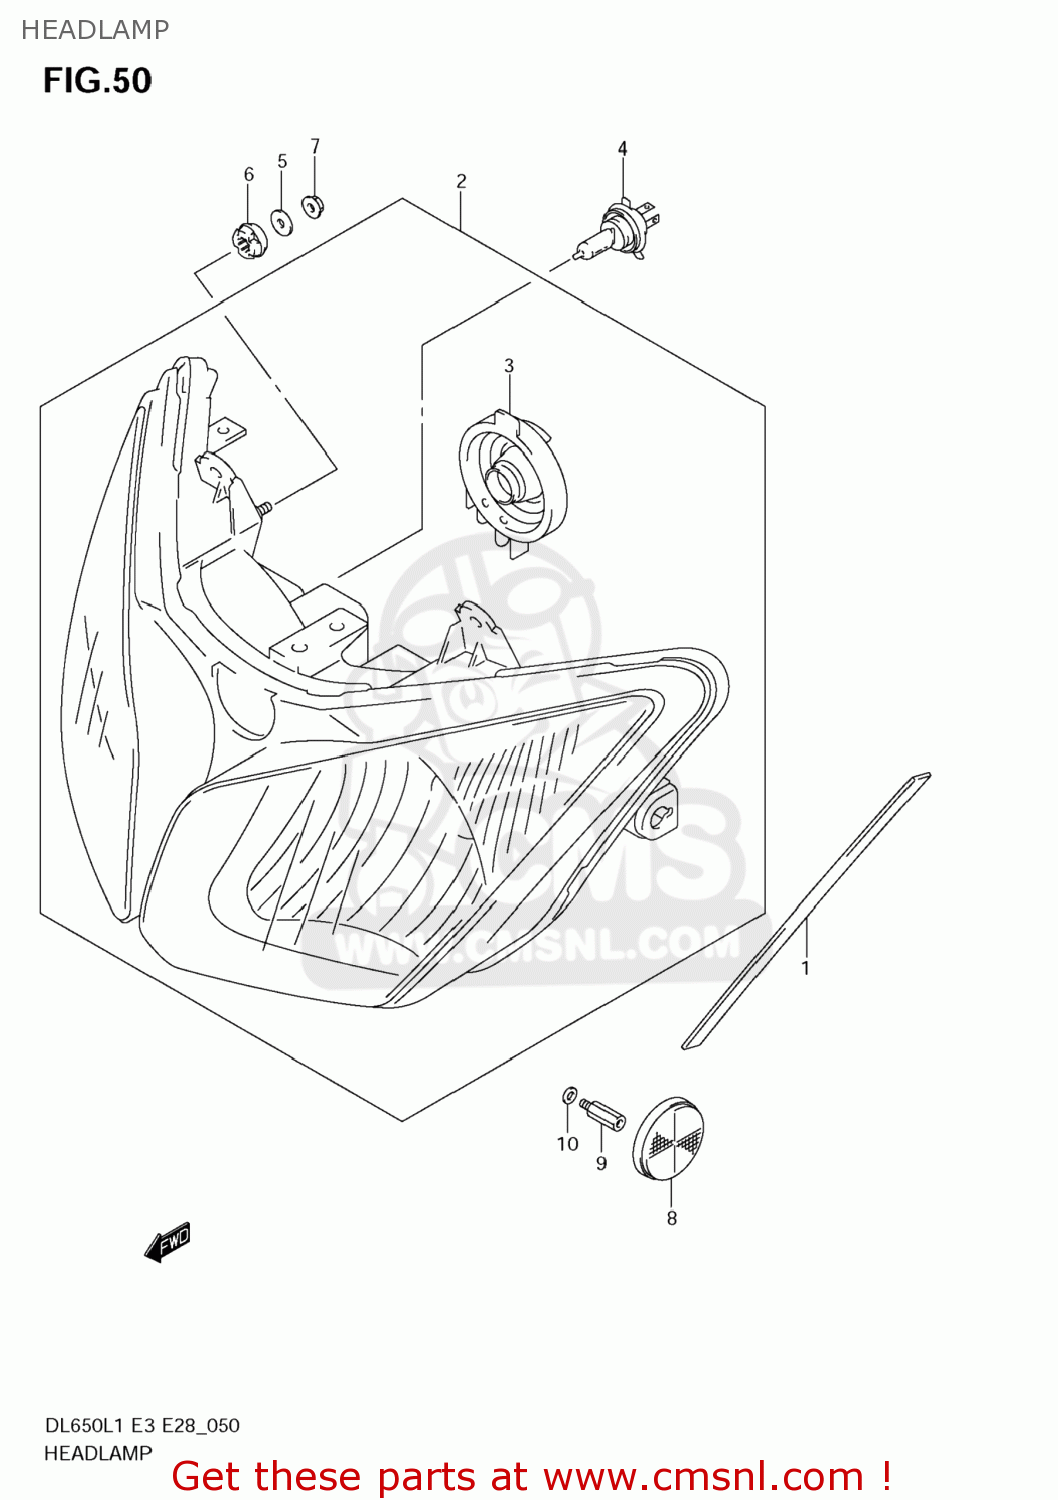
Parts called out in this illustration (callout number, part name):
1	CUSHION,HEADLAMP
2	HEADLAMP ASSY
3	COVER,SOCKET
4	BULB(12V60/55W,H4)
5	WASHER(6.5X20X1.6)
6	CUSHION
7	NUT
8	REFLEX REFLECTOR ASSY,FR SIDE
9	BOLT(5X10)
10	WASHER
